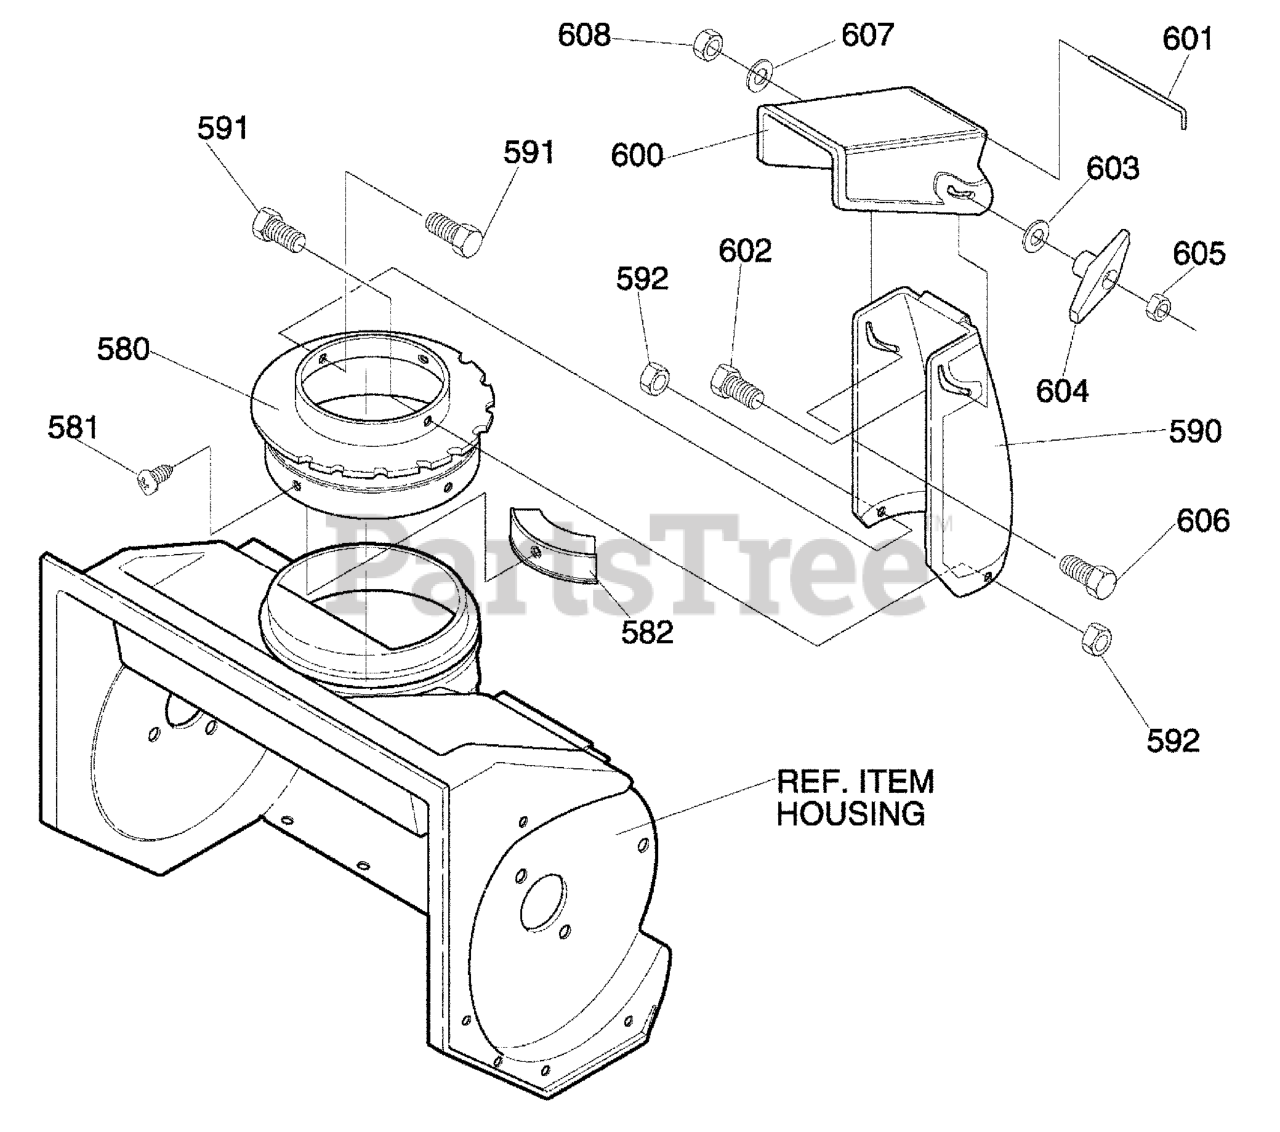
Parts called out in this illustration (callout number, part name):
580	RING, CHUTE
581	SCREW, #10X.50 HHTAPPST
582	GUIDE, CHUTE
590	CHUTE, LOWER
591	SCREW 1/4-20X.50
592	NUT, CNTRLK 1/4-2
600	CHUTE, UPPER
601	WIRE, HINGE
602	BOLT, 5/16-18X1.25 CARR.
603	WASHER, FLAT .349X.69X.066
604	KNOB, T
605	NUT, 5/16-18 REGHEX
606	SCREW, 5/16-18 x 0.75
607	WASHER, FLAT .349X.69X.066
608	NUT, 5/16-18 REGHEXCTRLK
